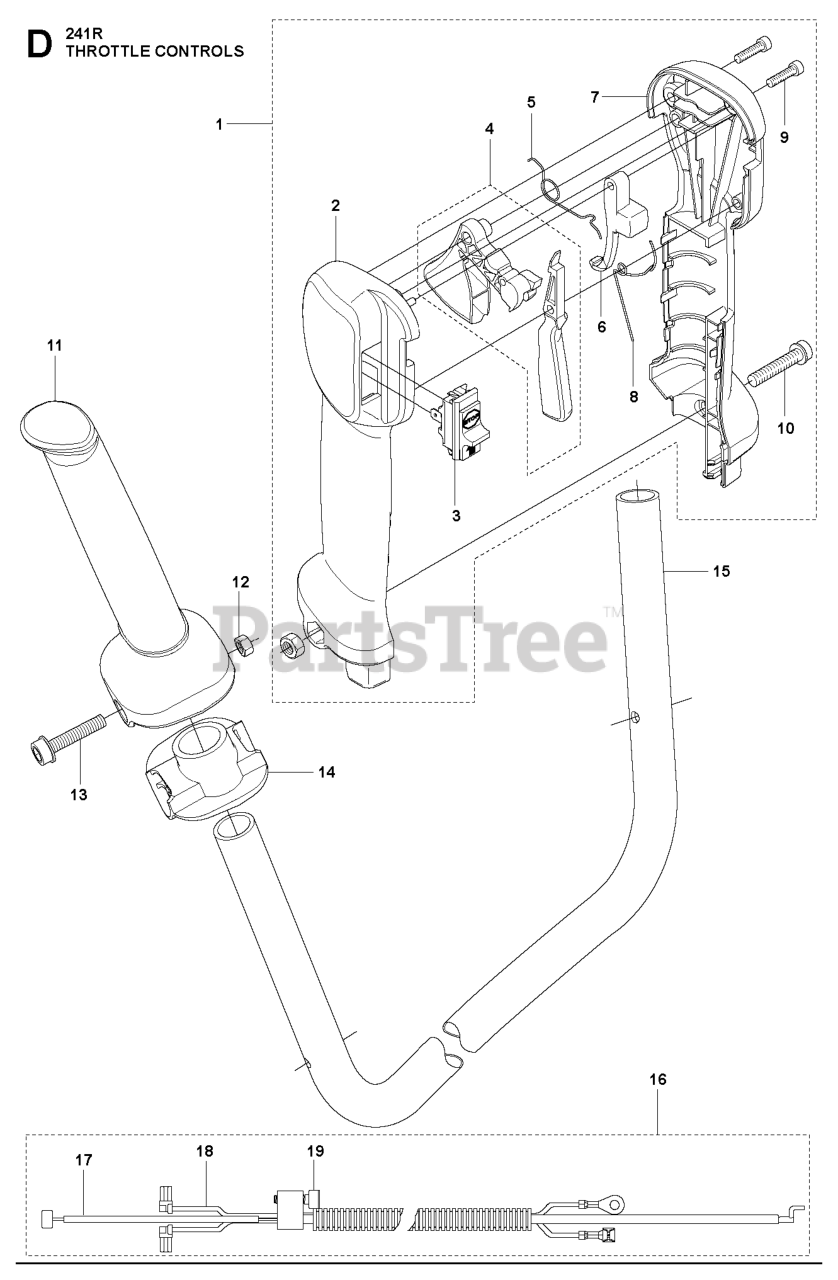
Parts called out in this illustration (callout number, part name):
1	HANDLE SYSTEM ASSY.
3	STOP BUTTON
4	THROTTLE CONTROL
6	STARTER THROTTLE LOCK
10	SCREW
16	WIRING KIT COMPLETE
17	THROTTLE WIRE
18	SHORT CIRCUIT CABLE
